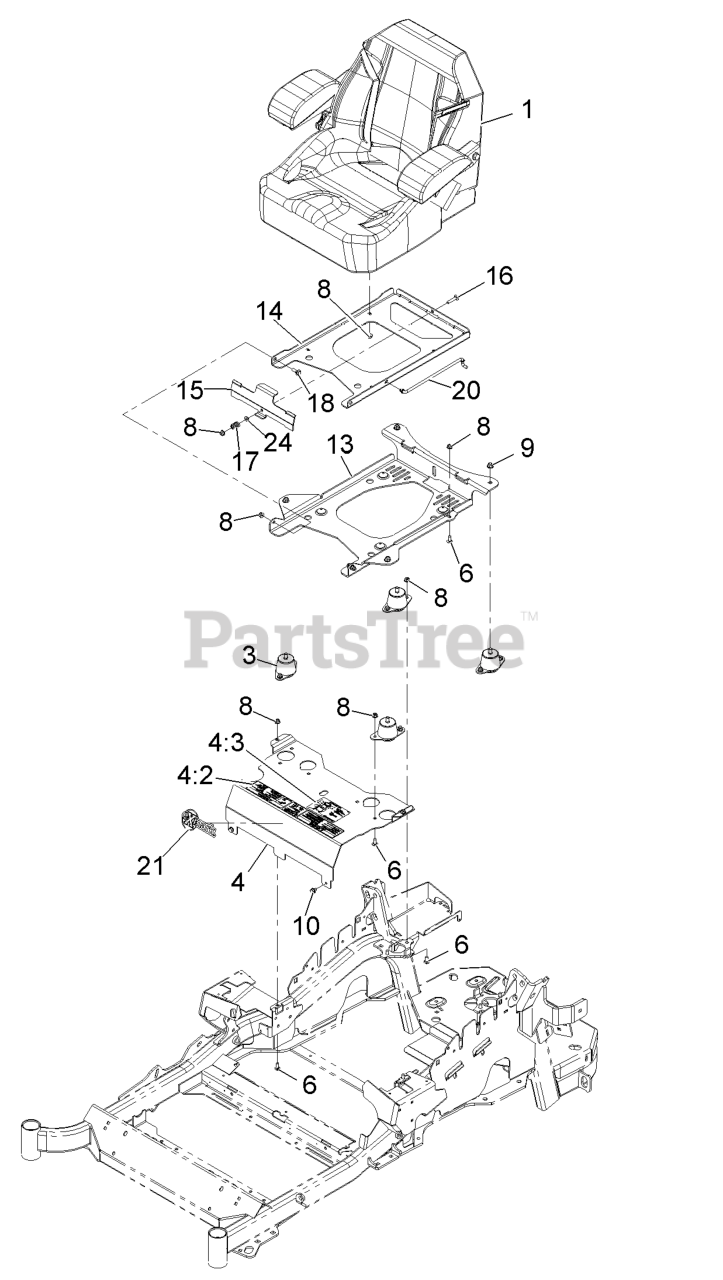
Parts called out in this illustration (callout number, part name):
3	ISOLATOR-SEAT
4	MOUNT-SEAT
4:2	DECAL-CONSOLE
4:3	DECAL-SERVICE AID
6	SCREW-CARR
8	NUT-HF, NI
9	NUT-HF, NI
13	PLATE-SUPPORT, SEAT TILT
14	PLATE-FRAME, SEAT TILT
15	PLATE-LATCH, SEAT
16	BOLT-CARR
17	SPRING-COMPRESSION
18	SCREW-SHOULDER
20	ROD-PROP
24	WASHER-PLAIN
